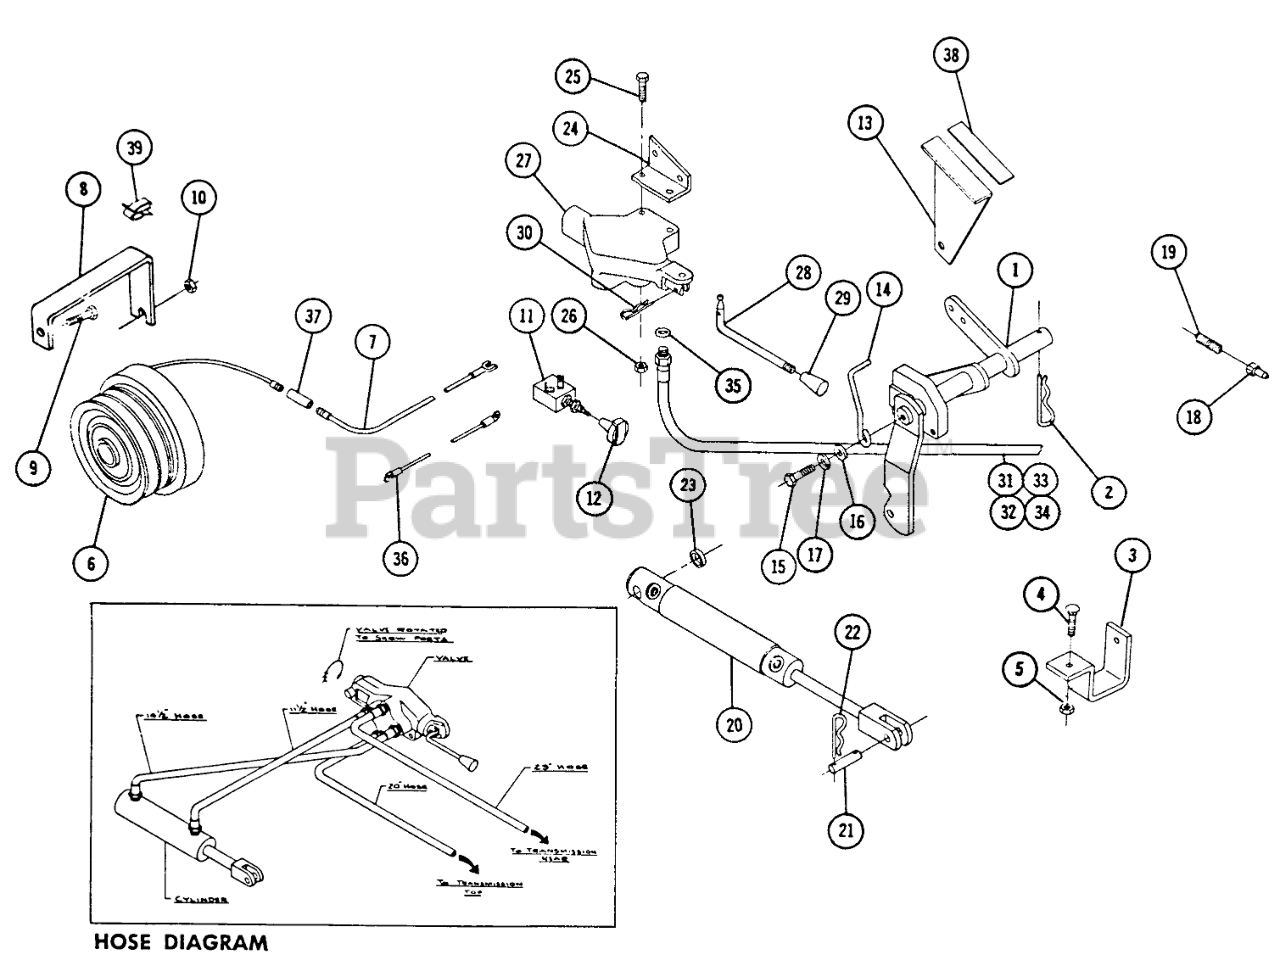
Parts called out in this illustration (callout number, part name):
1	Lift Arm
2	Hairpen
3	Bracket
4	Bolt-Carriage 5/16-18
5	Nut 5/16-18
6	Ass-y. Clutch
7	Wire
8	BRACKET
9	Bolt Hex 7/16-4 x 3/4
10	Nut-Nylok 1/4-28
11	Switch
12	Knob
13	Indicator Plate
14	Arm
15	Bolt 5/16-18 x
16	Washer
17	Lockwasher
18	Cone
19	Spring
20	Cylinder
21	PIN
22	Hairpin
23	Spacer
24	SUPPORT-VALVE
25	Bolt 1/4 20 x 1 1/4
26	Nut-Nylok
27	Valve
28	VALVE LEVER
29	Knob
30	Hairpin
31	Ass-y. Hose-29"
32	Ass-y. Hose-20"
33	Ass-y. Hose-14-1/2"
34	Hose-111/2
35	O RING
36	Wire-Switch to Clutch
37	CONNECTOR 2 WIRE
38	Decal
39	CLIP-WIRE
